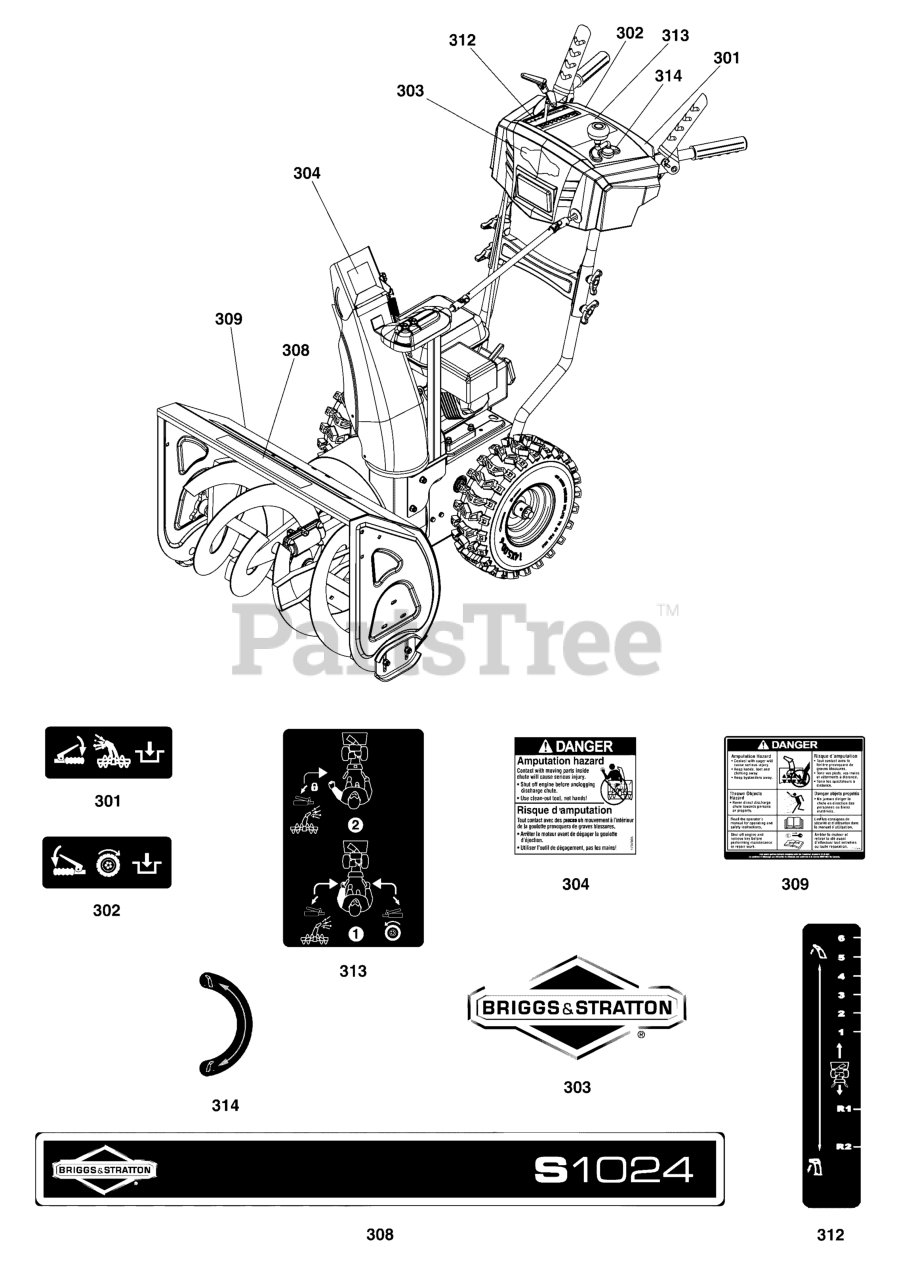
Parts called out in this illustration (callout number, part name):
1	KIT-DECAL, Briggs 1024MD
2	KIT-DECAL, Briggs 1024MD, Export
301	DECAL, Auger Control
302	DECAL, Traction Control
303	*DECAL, Control Panel, Briggs & Stratton
304	DECAL, Danger Chute Warning, FR/ENG
309	DECAL, Danger Foot, FR/ENG
312	DECAL, 1-6 Transmission Speed Control
313	DECAL, Free Hand Operation
314	DECAL, Chute Rotation
324	DECAL, Chute Warning, Export
329	DECAL, Danger Auger Icons
